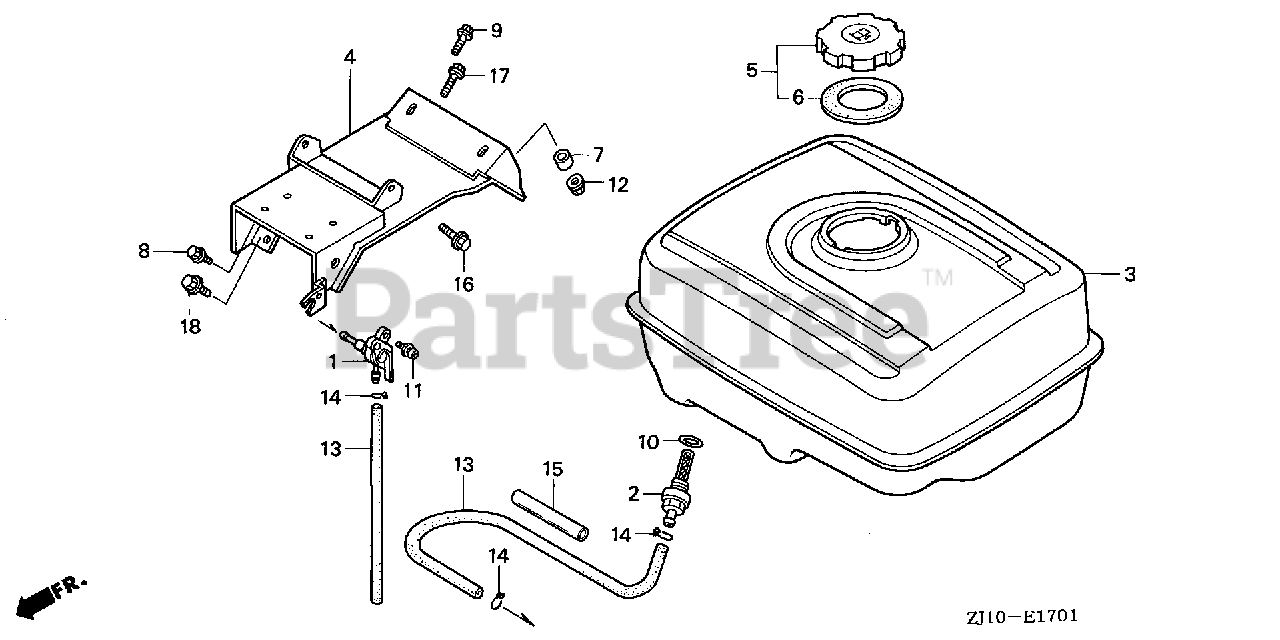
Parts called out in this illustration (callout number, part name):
1	PETCOCK ASSY.
2	JOINT, FUEL TANK
3	TANK, FUEL *NH1* (BLACK)
3	TANK, FUEL *R8* (BRIGHT RED)
4	STAY, FUEL TANK
5	CAP, FUEL FILLER (BLACK)
6	GASKET, FUEL FILLER CAP (39X58X3)
7	COLLAR, FR. ENGINE HANGER (A)
8	BOLT, FLANGE (6X23) (CT200)
9	BOLT, FLANGE (6X20) (CT200)
10	O-RING (13.5X1.5) (ARAI)
10	O-RING (14MM) (NOK)
11	SCREW-WASHER (5X14)
12	NUT, FLANGE (8MM)
13	BULK HOSE, FUEL (4.5X3000) (95001-450(95001-45001-60M)
14	CLIP, TUBE (B8)
15	BULK HOSE, VINYL (9X11X3000) (9X11X180)
16	BOLT, FLANGE (8X16)
17	BOLT, FLANGE (8X25)
18	BOLT, FLANGE (8X30)
